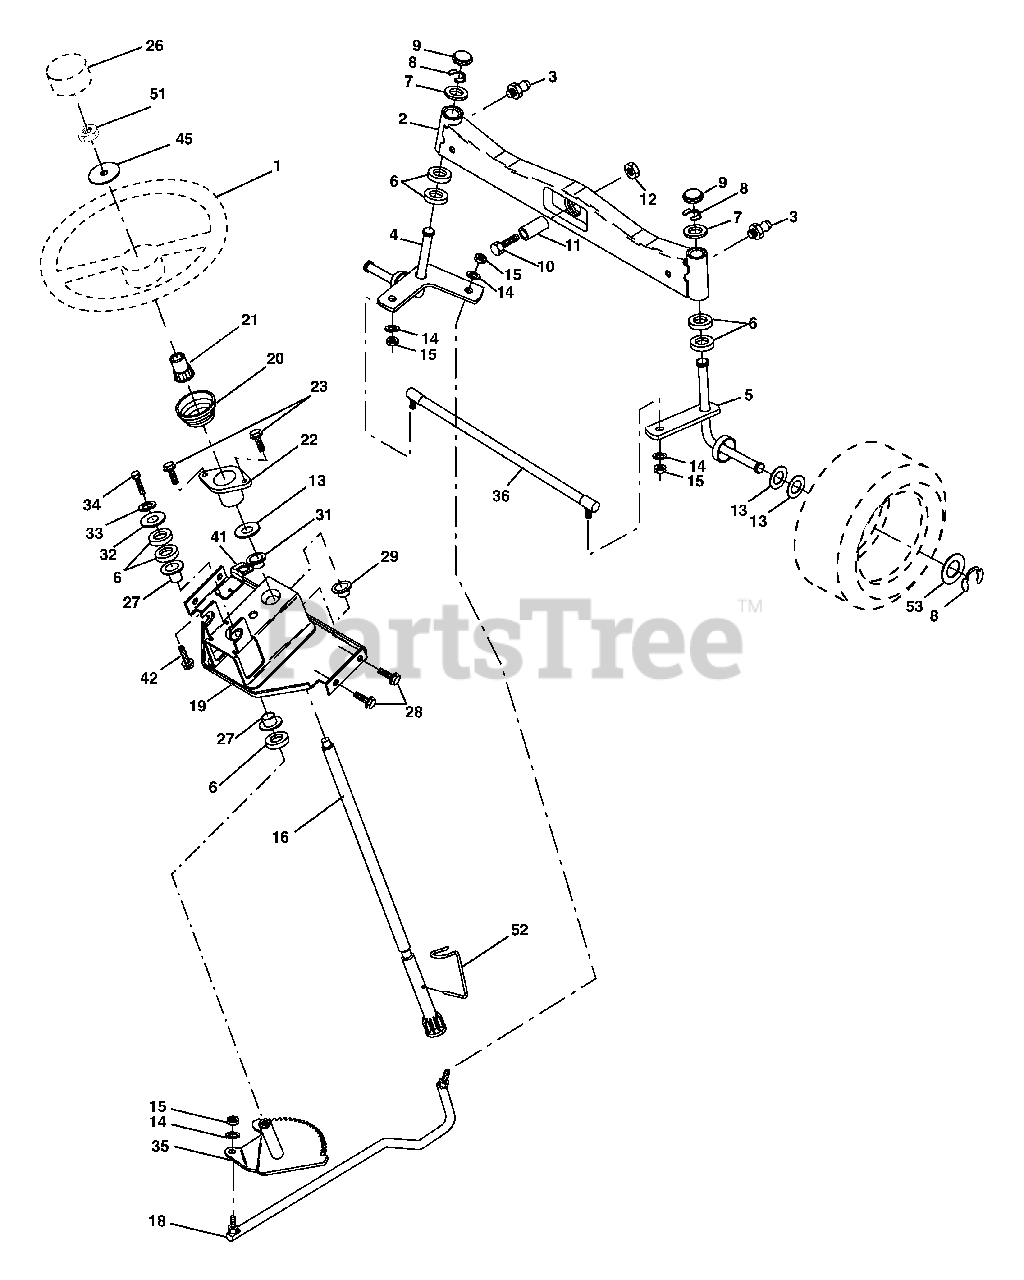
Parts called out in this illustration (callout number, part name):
1	Wheel, Steering
2	Axle Asm., Front
3	Fitting, Grease
4	Spindle Asm., LH
5	Spindle Asm., RH
6	Bearing, Race Thrust Harden
7	Washer 25/32 x 1-5/8 x 16 Ga.
8	Ring, Klip #T5304-75
9	Cap, Spindle
10	Bolt, Fin Hex 5/8-11 x 2-3/4
11	Spacer Bearing Axle Front
12	Nut, Lock Flange 5/8-11 unc
13	Washer 25/32 x 1-1/4 x 16 Ga.
14	Washer, Lock Hvy Hlcl Spr 3/8
15	Nut, Crown Lock 3/8-24 unf
16	Shaft Asm., Steering
18	Draglink, Vgt
19	Support Asm., Steering Vgt
20	Boot, Steering
21	Adapter, Wheel Steering
22	Bushing, Strg. Blk
23	Screw
26	Insert, Wheel Steering
27	Bearing, Col. Strg.
28	Screw 3/8-16 x 3/4
29	Bearing, Flange
31	Bushing, Nyliner Snap
32	Washer 11/32 x 1 x 10 Ga.
33	Washer, Lock Hvy Hlcl Spr 5/16
34	Bolt, Hex Hd 5/16-18 x 3/4
35	Gear, Sector Steering
36	Tie Rod
41	Bracket Switch Interlock VGT 97
42	Screw Thdrol 5/16-18 x 1/2 Tyt
45	Washer 9/16 x 2-3/8 x 12 Ga.
51	Nut Hex Jam Toplock 1/2-20 unf
52	Clip Steering
53	Washer Hardened .793 x 1.637 x .060
